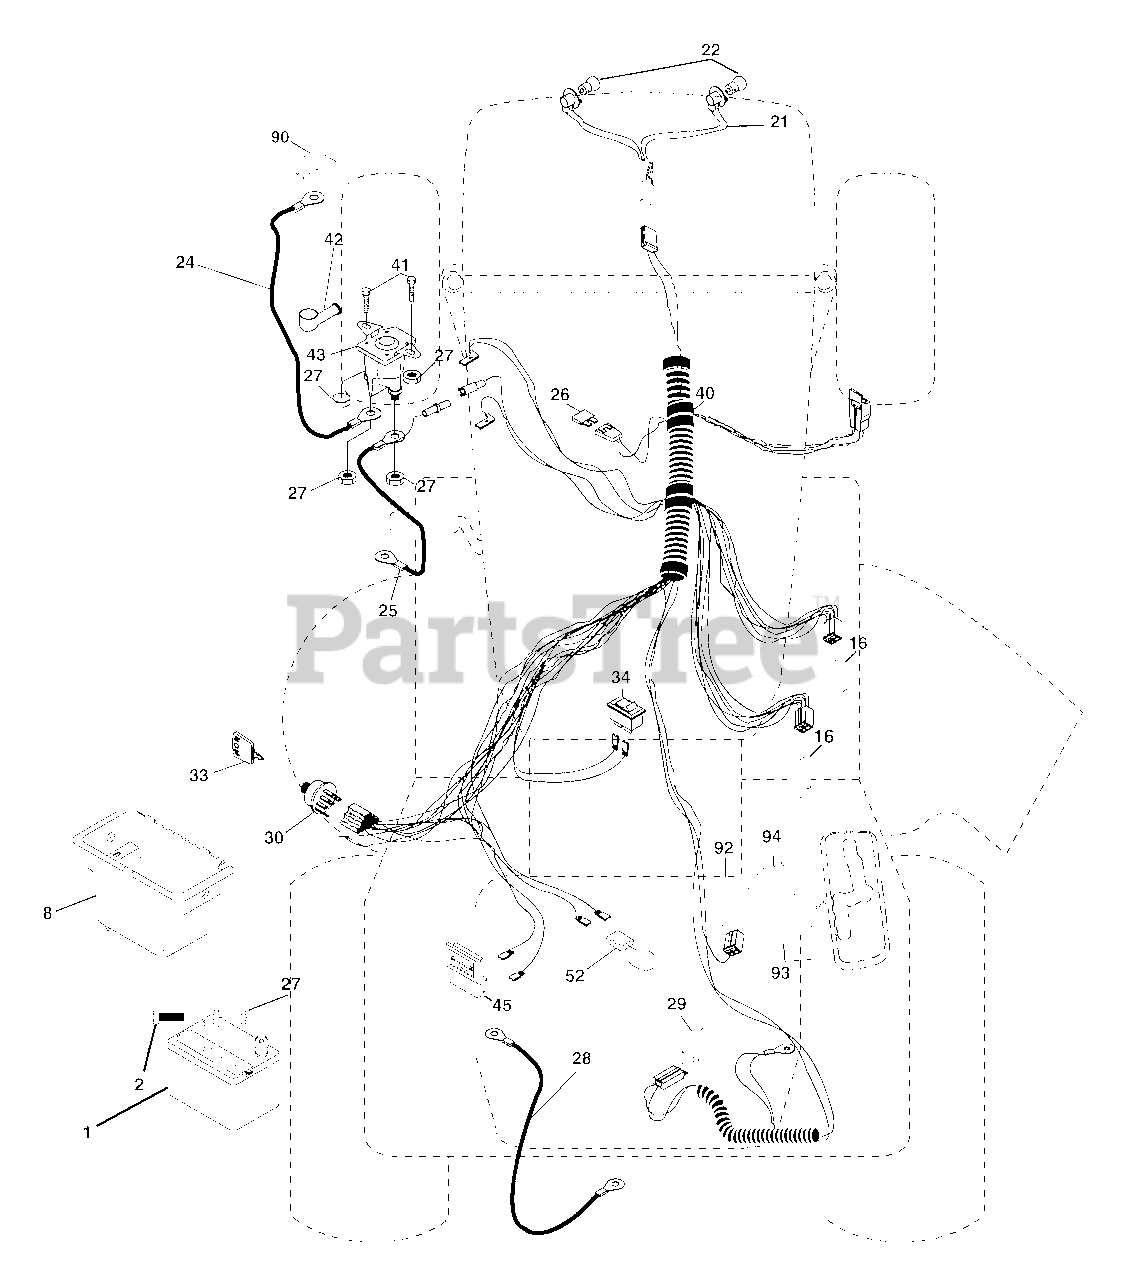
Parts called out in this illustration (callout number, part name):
1	Battery 12 Volt 25 Amp
2	Bolt Hex Hd 1/4-20 unc x 3/4
8	Box Battery
16	Switch Interlock Push -In
21	Harness Asm Light W/4152J
22	Bulb Light #1156
24	Cable Battery 6 Ga. 11" red
25	Cable Battery 6 Ga. w/16 wire,red
26	Fuse 20 AMP
27	Nut Keps Hex 1/4-20 unc
28	Cable Ground 6 Ga. 12" black
29	Switch Seat
30	Switch Ign
33	Key Ign
34	Switch Light/Reset
40	Harness Ign
41	Bolt Blk Fin Hex 1/4-20 x 1/2
42	Cover Terminal Red
43	Solenoid
45	Ammeter
52	Protection Wire Loop
90	Cover Terminal
92	Harness Pigtail
93	Screw Plastite 10-14 x 2.0
94	Module Reverse
